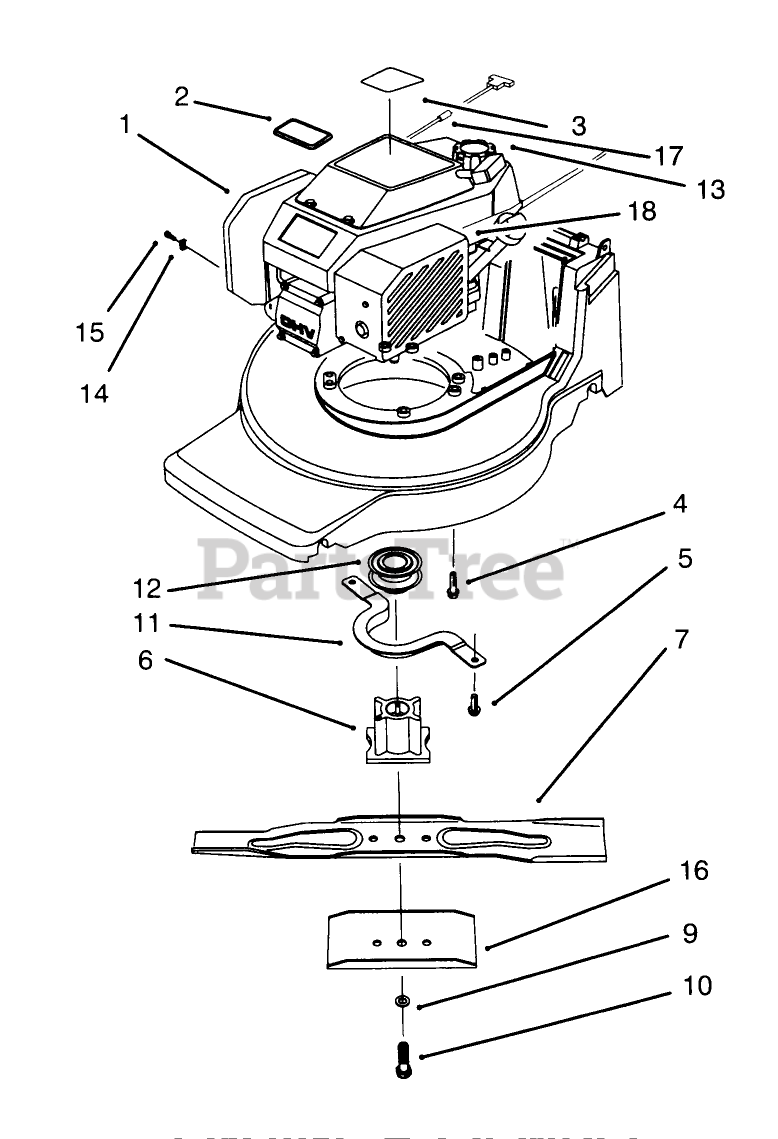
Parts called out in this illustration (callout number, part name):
1	Engine
2	PLATE-LOGO
3	DECAL - ENGINE
4	SCREW-HWH
5	SCREW-HWH
6	BLADE RETAINER - 25 MM
7	Blade
9	WASHER-LOCK
10	BOLT-BLADE
11	Guide-Belt
12	PULLEY-DRIVE, ZONE START
13	CAP-GAS
14	CLAMP-CASING
15	CLAMP SCREW F/W ENGINE
16	Stiffener Blade
17	STOP-ROPE
18	COVER - BRAKE F/W
